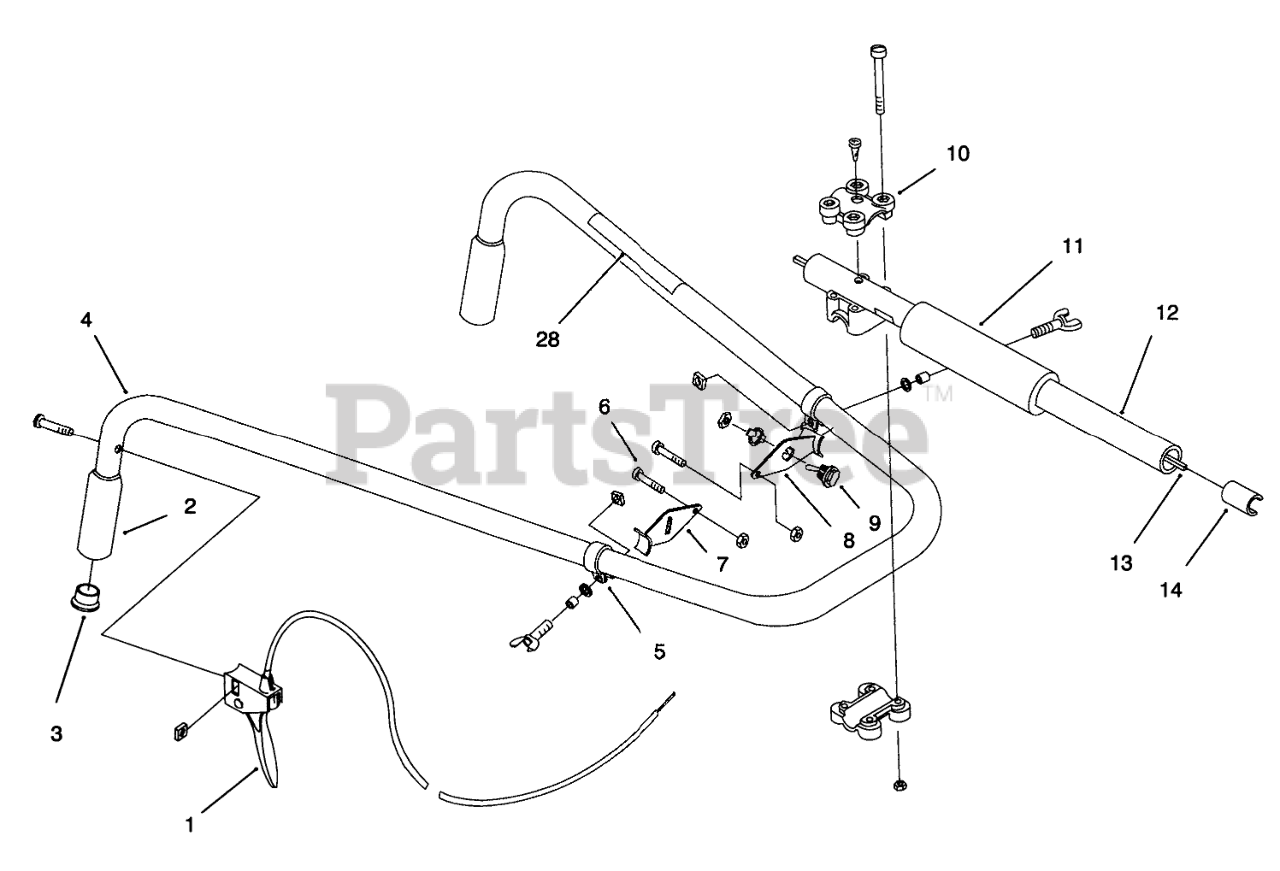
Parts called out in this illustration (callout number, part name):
1	ASM - THROTTLE
2	HANDLE NITRILE GRIP
3	TUBE CLOSURE
4	DRIVE SHAFT ASM
5	ASSEMBLY - CLAMP
6	HARDWARE-ENGINE MTG BRKT
7	BRACKET- RH ENGINE MTG
8	BRACKET - LH ENGINE MOUNT
9	SWITCH ASM
10	HANDLE BRACKET ASM
12	Drive Shaft Housing Asm.
13	SHAFT - FLEXIBLE DRIVE
14	SLEEVE - RETAINER
28	Decal-Safety Symbol
